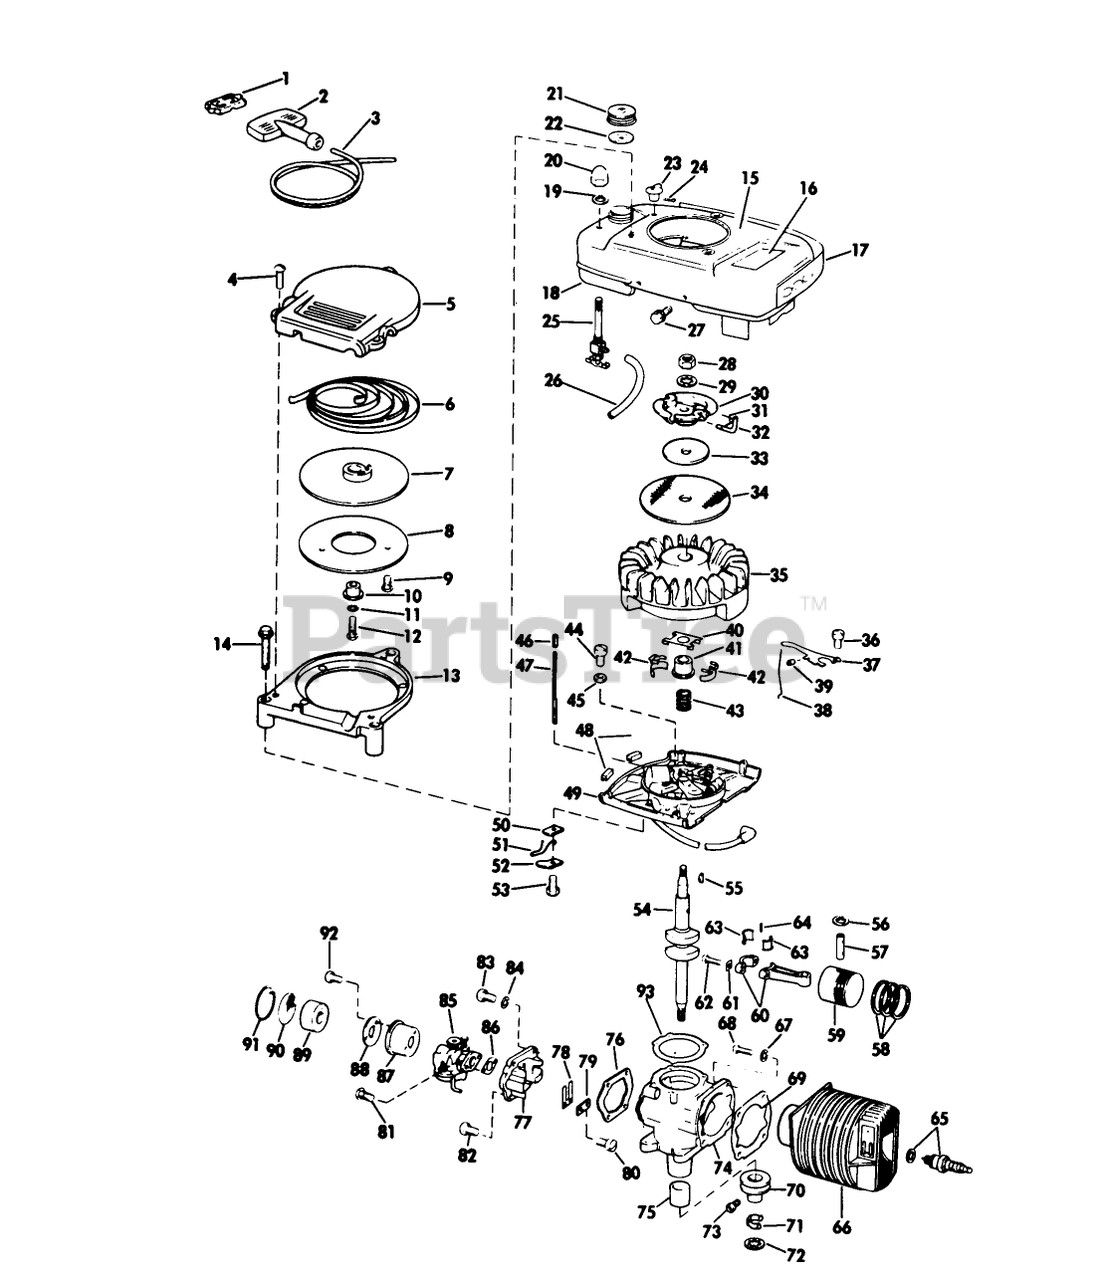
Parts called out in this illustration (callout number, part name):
6	RECOIL SPRING
8	Plate-Pulley
20	PALNUT S
23	KNOB, CHOKE BAR
24	Cotter Pin-Choke Knob
25	VALVE&SCREEN SM
27	SCREW S
32	PIN - STARTER
37	GOVERNER LEVER AY
38	GOVERNOR ROD S
39	WEAR BLOCK S
41	COLLAR S
53	Screw Shut-off Switch
56	RING-RETAINING
63	LINER ASM
69	GASKET S
79	PLATE-BACKUP, REED
82	SCREW S
83	SCREW S
86	GASKET S
88	BACK-UP PLATE
89	ELEMENT
93	GASKET S
